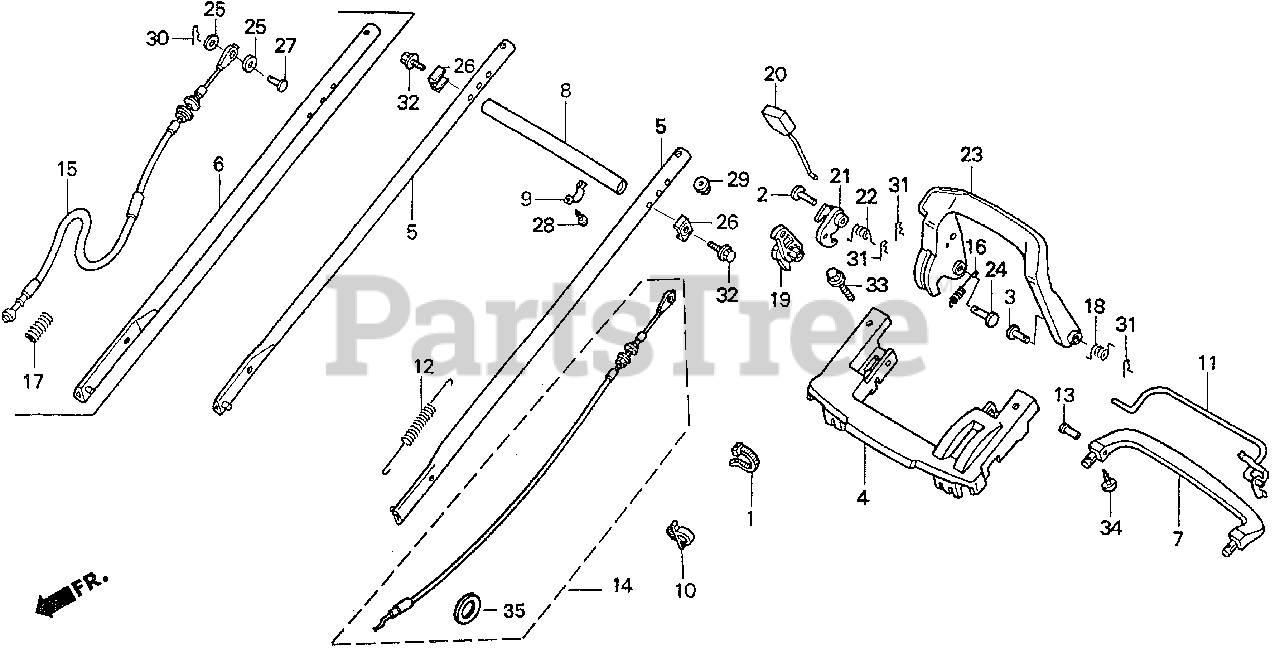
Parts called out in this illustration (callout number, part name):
1	TIE, CABLE (157.5MM)
2	PIN, STEP BAR JOINT
3	PIN, STEP BAR JOINT
4	HANDLE (UPPER)
5	HANDLE (LOWER) *NH246* (LOOSY GRAY) (NOT AVAILABLE)
7	GRIP, HANDLE
8	PIPE, HANDLE CONNECTING *NH246* (LOOSY GRAY)
9	PLATE, HANDLE CONNECTING
10	CLIP, POWER STEERING SUCTION TUBE
13	PIVOT, CLUTCH LEVER
15	CABLE, ROTO-STOP CLUTCH
18	SPRING, R. STOP RETURN
19	ARM, ROTO-STOP CABLE
20	ROD, RATCHET PUSH
21	LEVER, LOCK
22	SPRING, RATCHET PIN
23	LEVER, ROTO-STOP
24	PIN, SEAT BASE (8MM)
26	WASHER, FRAME JOINT
27	PIN, CABLE JOINT (6X17)
28	SCREW, TAPPING (4X10) (PO)
29	NUT, SELF-LOCK (8MM) (CLINCH)
29	NUT, FLANGE (8MM)
30	PIN, LOCK (6MM)
31	PIN, LOCK (8MM)
32	BOLT, FLANGE (6X45)
33	BOLT, FLANGE (8X45)
34	SCREW, TAPPING (3.5MM)
